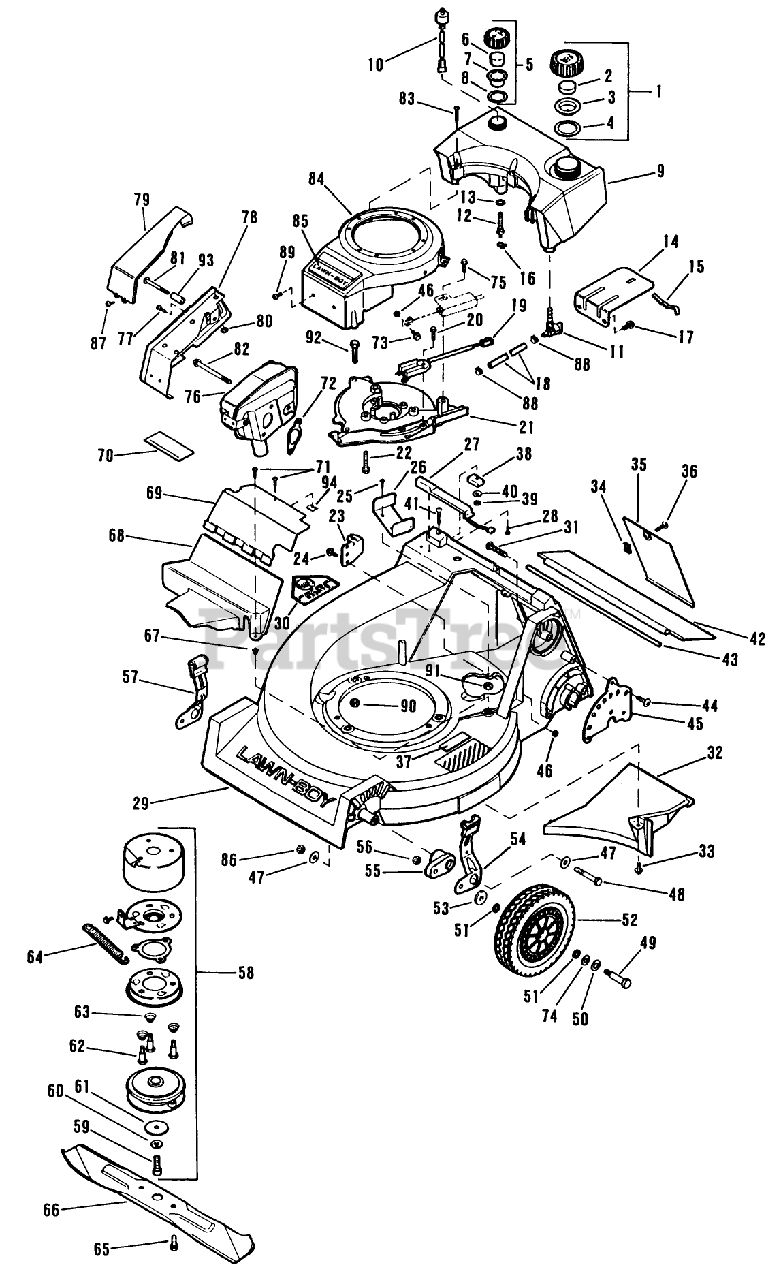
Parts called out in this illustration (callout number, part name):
1	CAP AY - FUEL M
2	BAFFLE - FOAM SM
4	GASKET-FUELCAP SM
5	CAP AY. OIL M
6	FILTER S
10	SWITCH AY,OIL S
11	DISC/LB SER.BUL.#6
14	DISC. LB SER.BUL.#6
15	SPRING
18	GAS LINE SM
19	SWITCH INT.LOCK S
22	SCREW-SEMS F
26	BELT GUIDELB
27	SWITCH AY DELTA
32	CHUTE BAFFLE NYL
34	SPEED NUT LARSON
35	DOOR-ACCESS ELECT.
36	SCREW-CROSS RECESS
44	SCREW-BHTF
45	PLATE HGT CMS
46	LOCKNUT E
47	WASHER-PLAIN
49	BOLT WHEEL QUAL
50	SPACER
51	WASHER
52	WHEEL&TIRE 8" TRI
53	WASHER
54	KNOB & SPRING CMS
55	ARM HGT ADJ *BLACK
56	NUT-JAM, LOCKING
57	KNOB & SPRING CMS
61	WASHER
62	SCREW,SHOULDER SM
64	SPRING
65	SCREW SEMS
66	21" Blade
67	NUT-CLIP
71	SCREW S
72	GASKET - EXH SM
74	WASHER
75	SCREW-HH
77	SCREW S
78	MUFFLER GUARD AY
79	COVER MUFFLER CP
80	NUT-PUSH
81	SCREW SM
82	SCREW-SEMS
83	DISC.LB SER.BUL.#6
85	APPLIQUE SM
86	LOCKNUT
87	SCREW SM
88	HOSE CLAMP SM
90	NUT-LOCK F
91	NUT C/LOCK E
92	SCREW
93	SPACER S
94	NUT-SPEED
